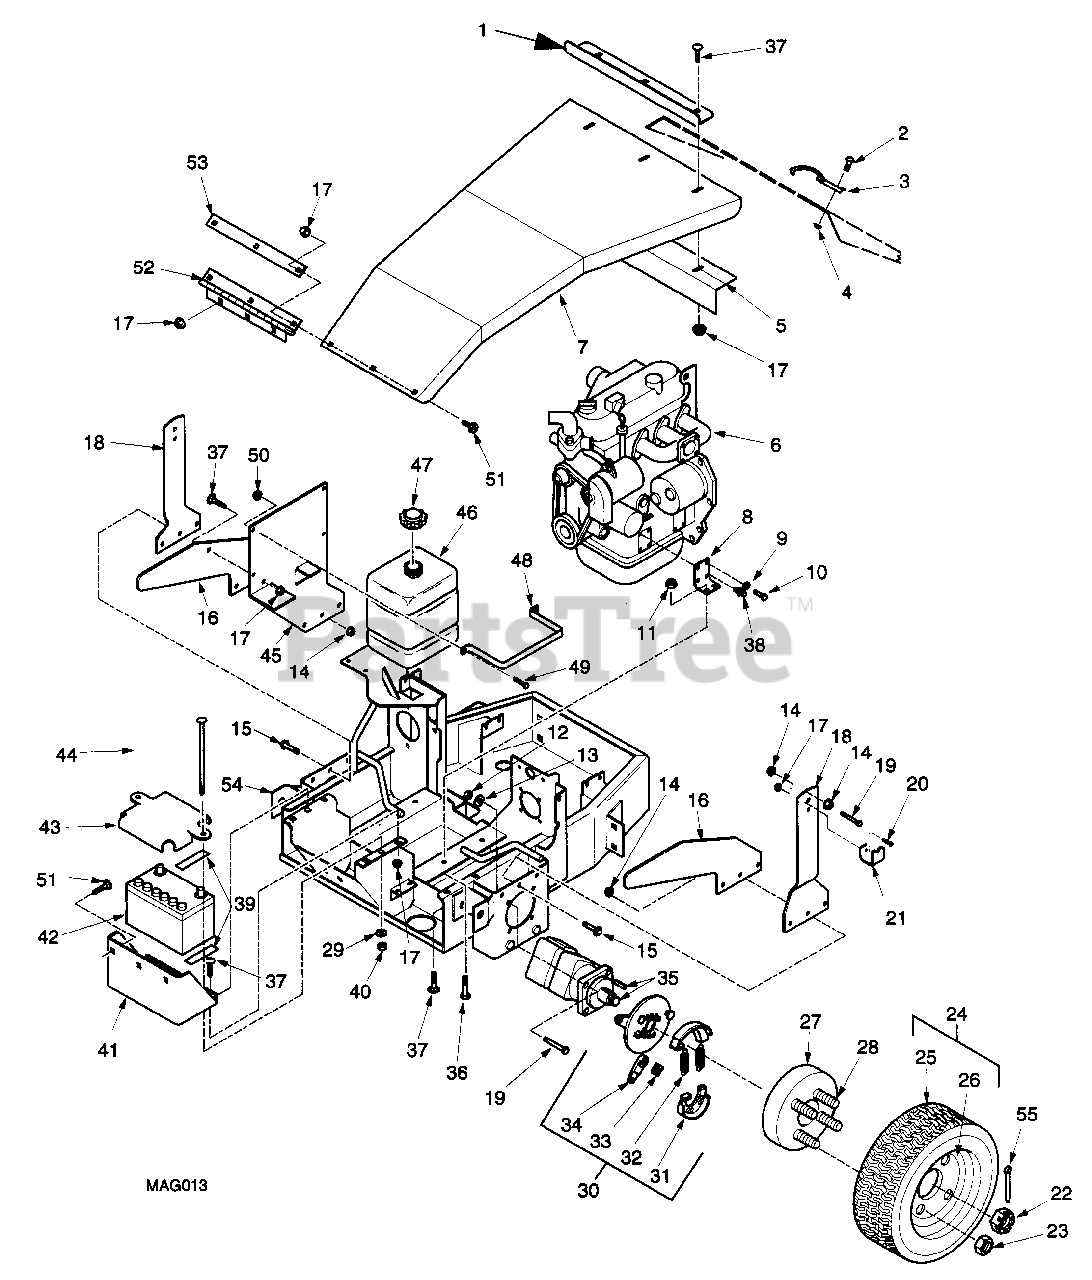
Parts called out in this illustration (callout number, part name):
1	CATCH, HOOD LATCH
2	SCREW, ROUND HEAD WASHER, #10-32 X 1/2
3	LATCH, HOOD
4	HEX NUT, #10-32
5	STIFFENER, HOOD
6	ENGINE, KUBOTA, 28 HP DIESEL
8	MOUNTING PLATE, ENGINE
9	LOCKWASHER, 7/16
10	BOLT, HEX HEAD, M10 - 1.25 X 25
11	HEX LOCKNUT, ELASTIC STOP, 7/16-14
12	HEX NUT, 1/2-13
13	LOCKWASHER, 1/2
14	SERR. FL. HEX NUT, 1/2-13
15	SERR. FL. HEX HEAD CAPSCREW, 1/2-13 X 1-1/2
16	STOP, CUTTER DECK
17	SERR. FL. HEX NUT, 5/16-18
18	ANCHOR, DECK SPRING
19	BOLT, HEX HEAD, 1/2-13 X 2-1/2
20	SERR. FL. HEX HEAD CAPSCREW, 5/16-18 X 3/4
21	RETAINER, SPRING
22	CASTLE NUT, 1.0-20 UNEF
23	NUT, WHEEL
24	WHEEL ASSEMBLY(INCLUDES 25, 26)
25	TIRE, 23 X 1050 - 12, 4-PLY
27	HUB, WHEEL(INCLUDES 28)
28	BOLT, HUB
29	FLAT WASHER, 5/16(.375 X .875 X .083)
30	PARKING BRAKE ASSEMBLY(INCLUDES 31,32,33,34)
31	BRAKE PADS - PAIR
32	SPRINGS - PAIR
34	ACTUATING ARM
35	MOTOR, HYDRAULIC - WHITE(INCLUDES 22)
36	BOLT, HEX HEAD, 7/16-14 X 1-1/4
37	CARRIAGE BOLT, 5/16-18 X 3/4
38	STUD, METRIC
39	PAD, RUBBER
40	HEX LOCKNUT, ELASTIC STOP, 5/16-18
41	BATTERY BOX
42	BATTERY
43	HOLD DOWN, BATTERY
44	CARRIAGE BOLT, 5/16-18 X 10
45	SUPPORT BRACKET, HYDRAULIC TANK
46	HYDRAULIC TANK
47	CAP, HYDRAULIC TANK
48	STRAP, HYDRAULIC TANK
49	SERR. FL. HEX HEAD CAPSCREW, 1/4-20 X 3/4
50	HEX LOCKNUT, ELASTIC STOP, 1/4-20
51	CARRIAGE BOLT, 5/16-18- 1/2
52	HINGE
53	PLATE, HINGE
54	ENGINE DECK
55	PIN, COTTER, 5/32 X 1-1/2
